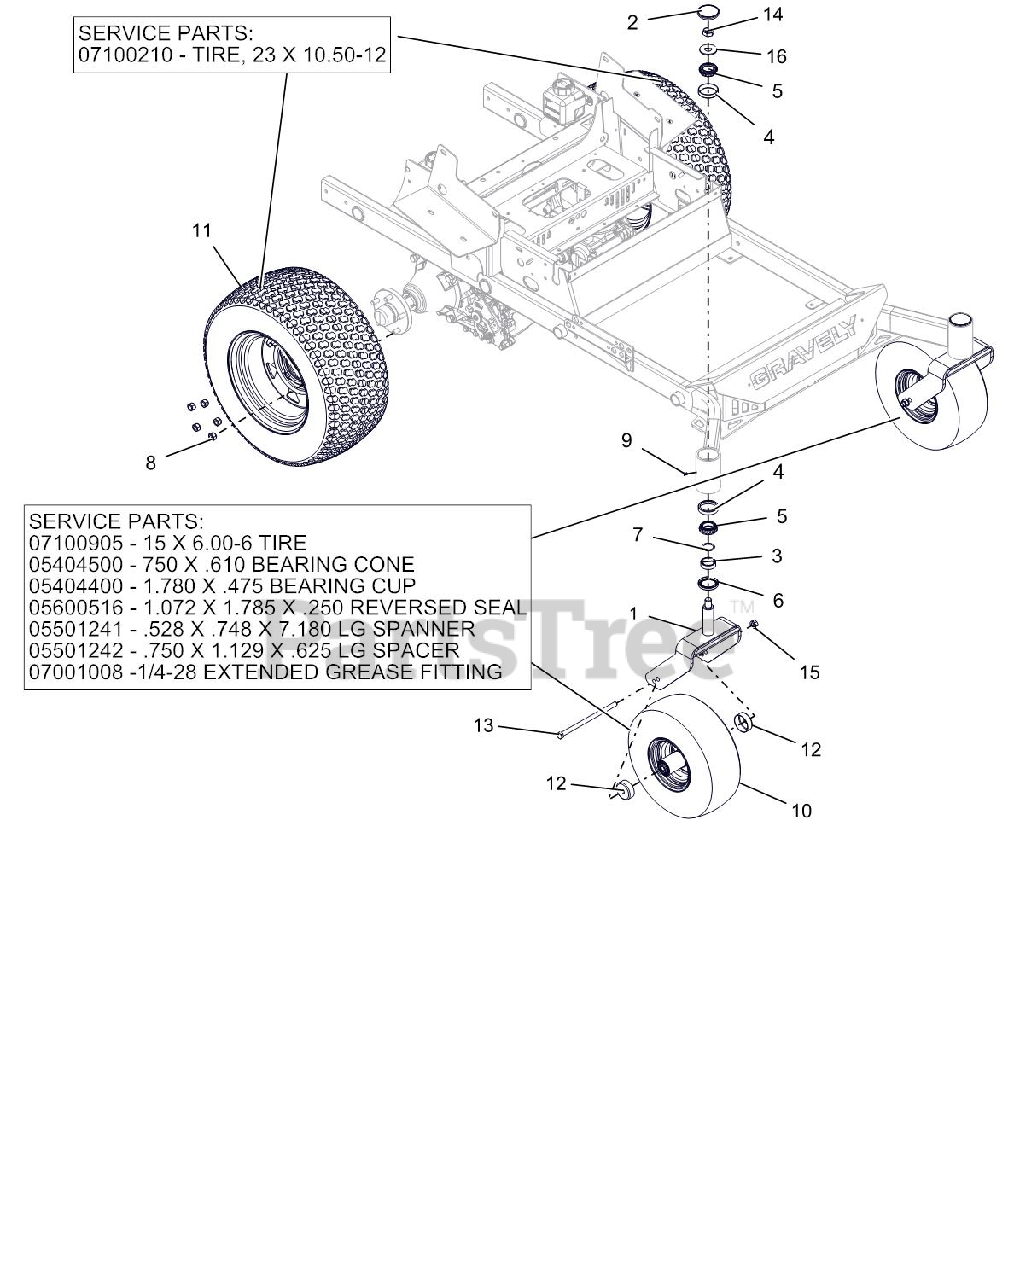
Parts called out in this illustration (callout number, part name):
1	CASTER FORK WMT - RED
2	CAP, DUST
3	SPCR, FRONT CASTER FORK
4	BRG-CUP 2.328X.465
5	BRG-CONE 1.25X.66
6	SEAL, OIL 1.75 X 2.332 X .312
8	WHEEL NUT .500-20 YZ
9	FTG, .25-28 FLUSH MNT GREASE
10	BRG-CONE .750X.61
10	BRG-CUP 1.781X.475
10	GREASE FITTING 1/4-28 EXTENDED
10	TIRE, 15X6-6 SMOOTH
10	SEAL,1.072X1.785X.250 REVERSED
10	ASM, WHL/TIRE 15X6.00-6 SMOOTH
10	SPANNER, .528X.748X7.18 LG
10	SPACER, .750X1.129X.625 LG
11	TIRE, 23X10.00-12
11	ASM, WHL/TIRE 23X10.50-12 K500
12	SHIELD, WHEEL BEARING
13	@BLT-HEX .50-13X9.00 GR5 YWZC
14	NUT-JAM TOPLK .75-16 YWZC
15	@NUT-LK-TOP-FLG .50-13 YWZC
16	@WSHR-FL-STL.812X2.00X.148YWZC
